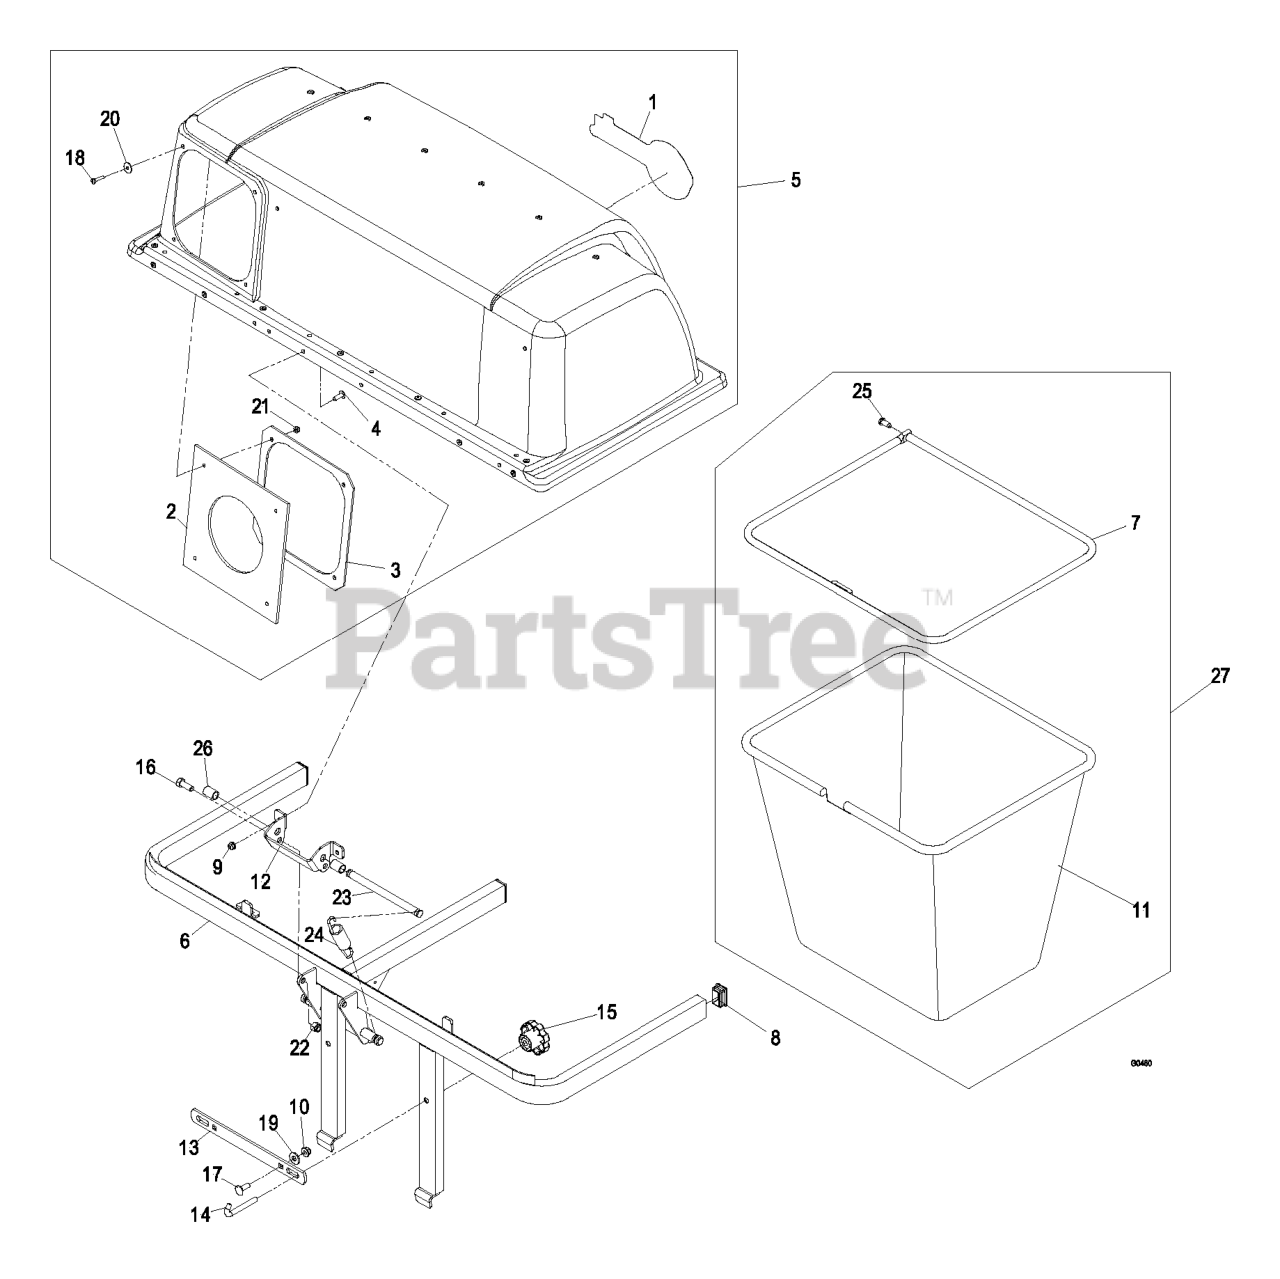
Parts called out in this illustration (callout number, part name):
1	DECAL, EXMARK LOGO
2	SEAL-CHUTE
3	CLAMP-SEAL
6	WLD,CT BAGGER MOUNT
8	CAP,TUBE
10	NUT-HF, NI
12	HINGE-BAGGER TOP
13	Bracket, Bagger Mt
14	ROD,FRAME MOUNT
16	SCREW-HH
17	BOLT-CARR
18	SCREW-PPH
19	WASHER-FLAT
20	WASHER-FLAT
21	NUT-LOCK, NI
22	NUT-LOCK, NI
23	PIN-SPRING
24	SPRING-EXTENSION
25	SCREW-BHTF
